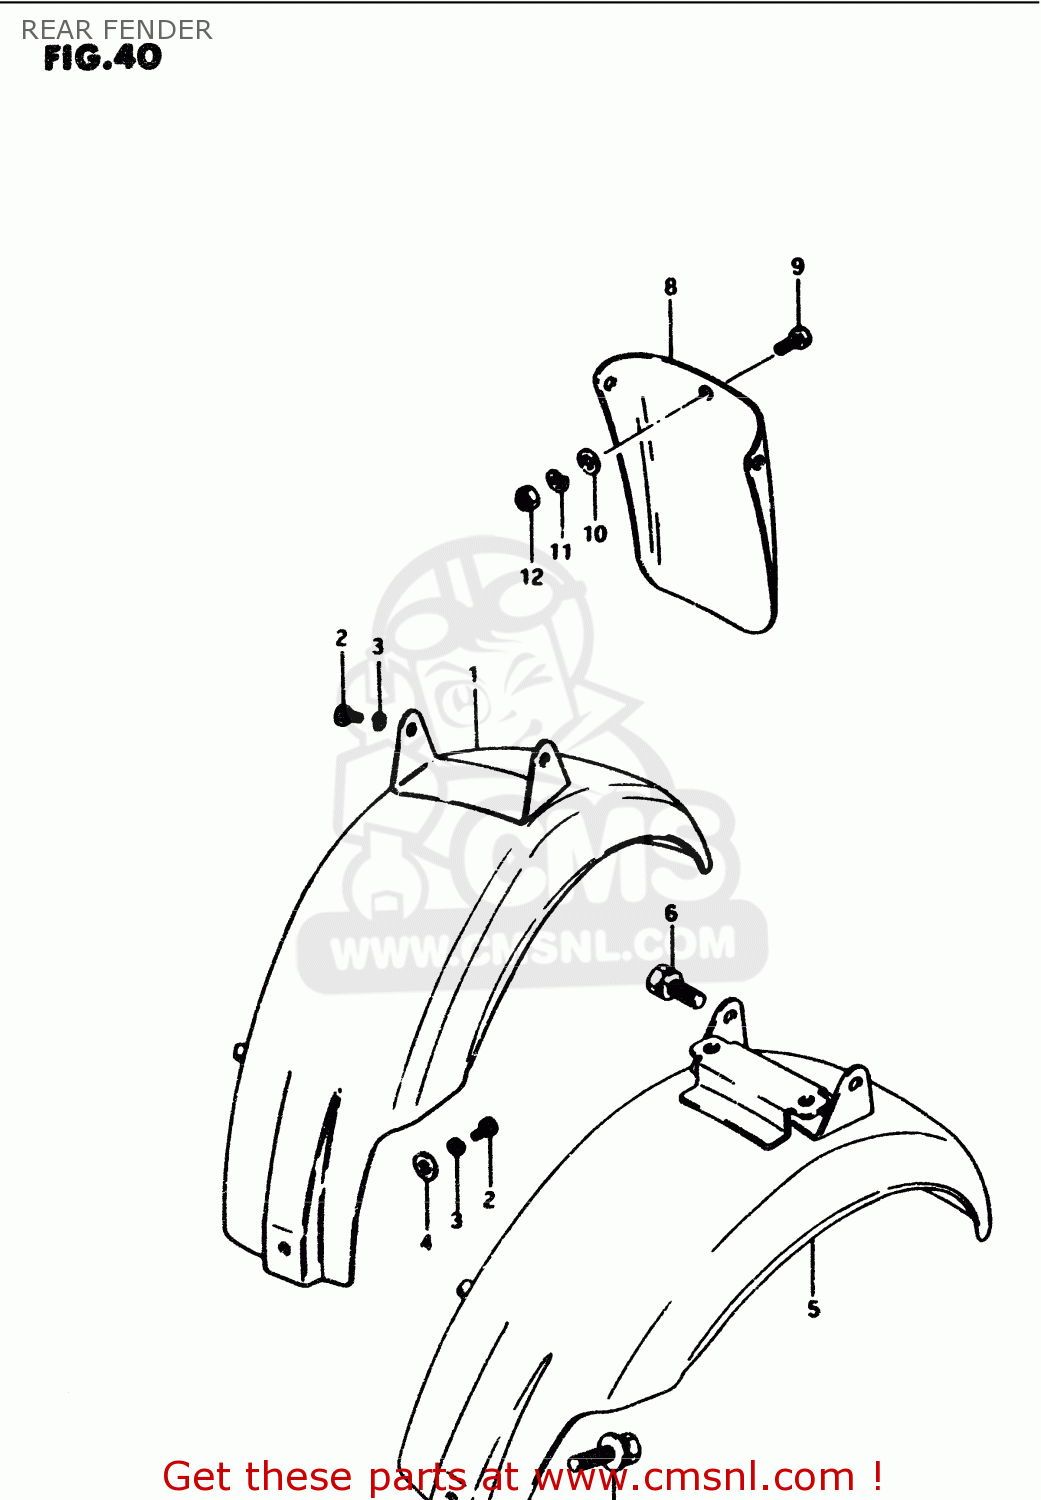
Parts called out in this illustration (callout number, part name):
1	FENDER,RR
2	BOLT
3	WASHER,LOCK
4	WASHER
5	FENDER,RR
6	BOLT
7	BOLT
8	FLAP,RR FENDER MUD
9	SCREW
10	WASHER
11	LOCK WASHER
12	NUT 6MM
